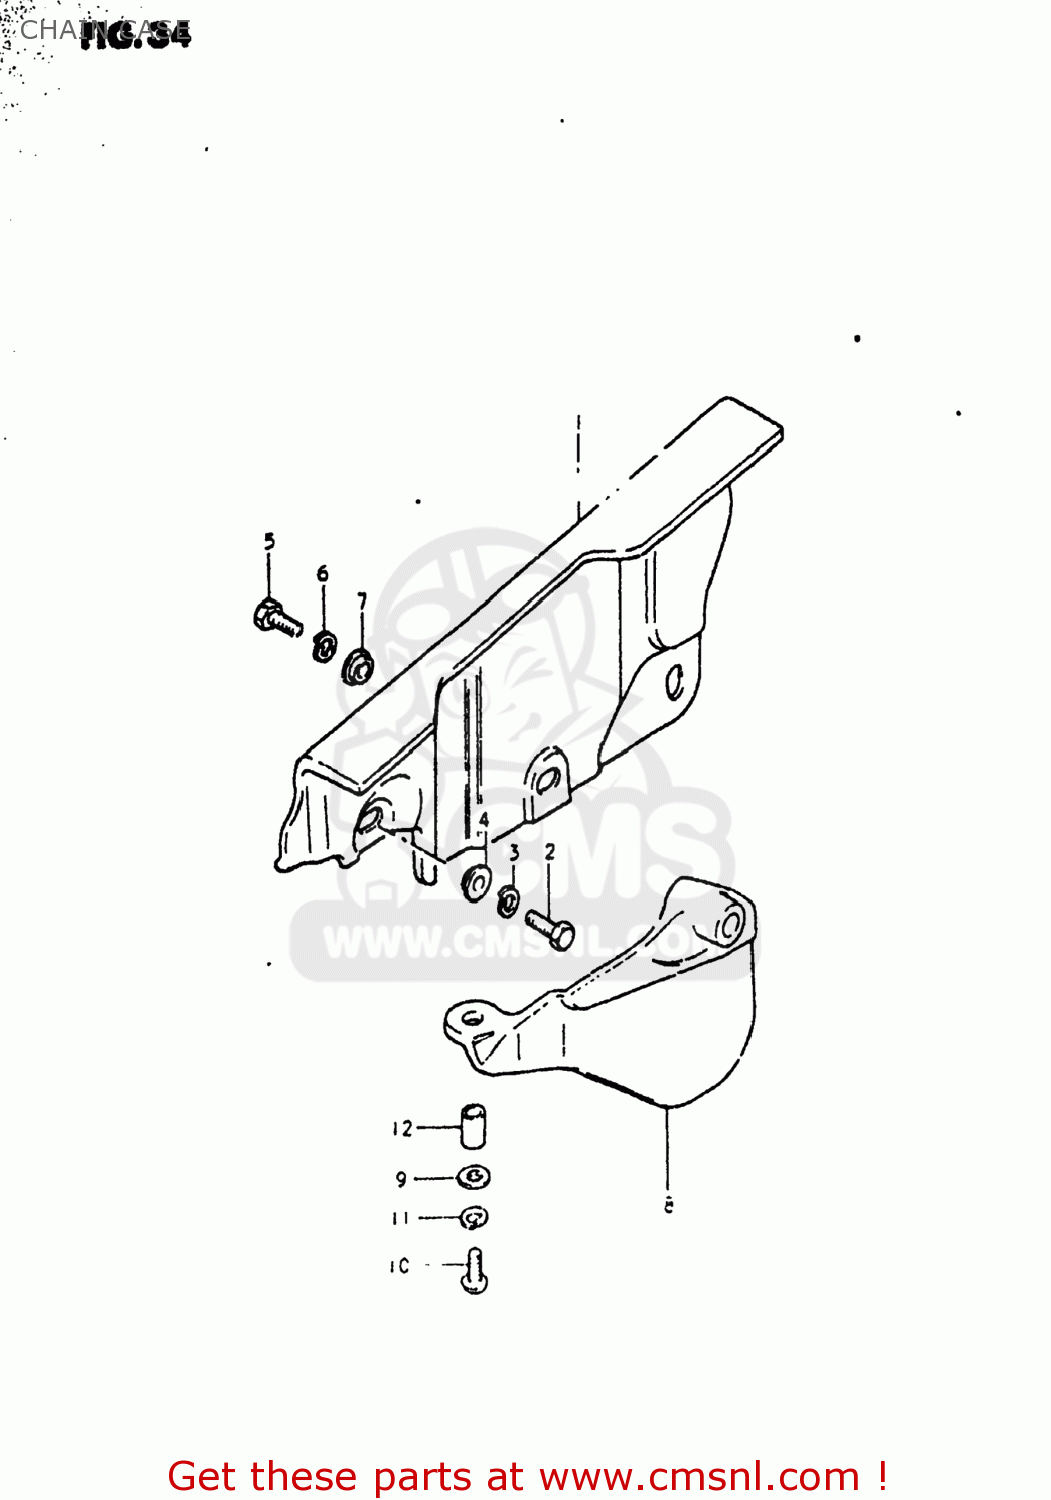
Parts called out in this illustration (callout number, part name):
1	CASE,CHAIN
2	BOLT, UPPER
3	LOCK WASHER
4	WASHER(6.5X18X1)
5	BOLT
6	LOCK WASHER
7	WASHER
8	RUBBER,CHAIN CASE,LOWER
9	SCREW 6X12
10	LOCK WASHER
11	WASHER(6.5X18X1)
12	SPACER (6.1X8X5.2)
